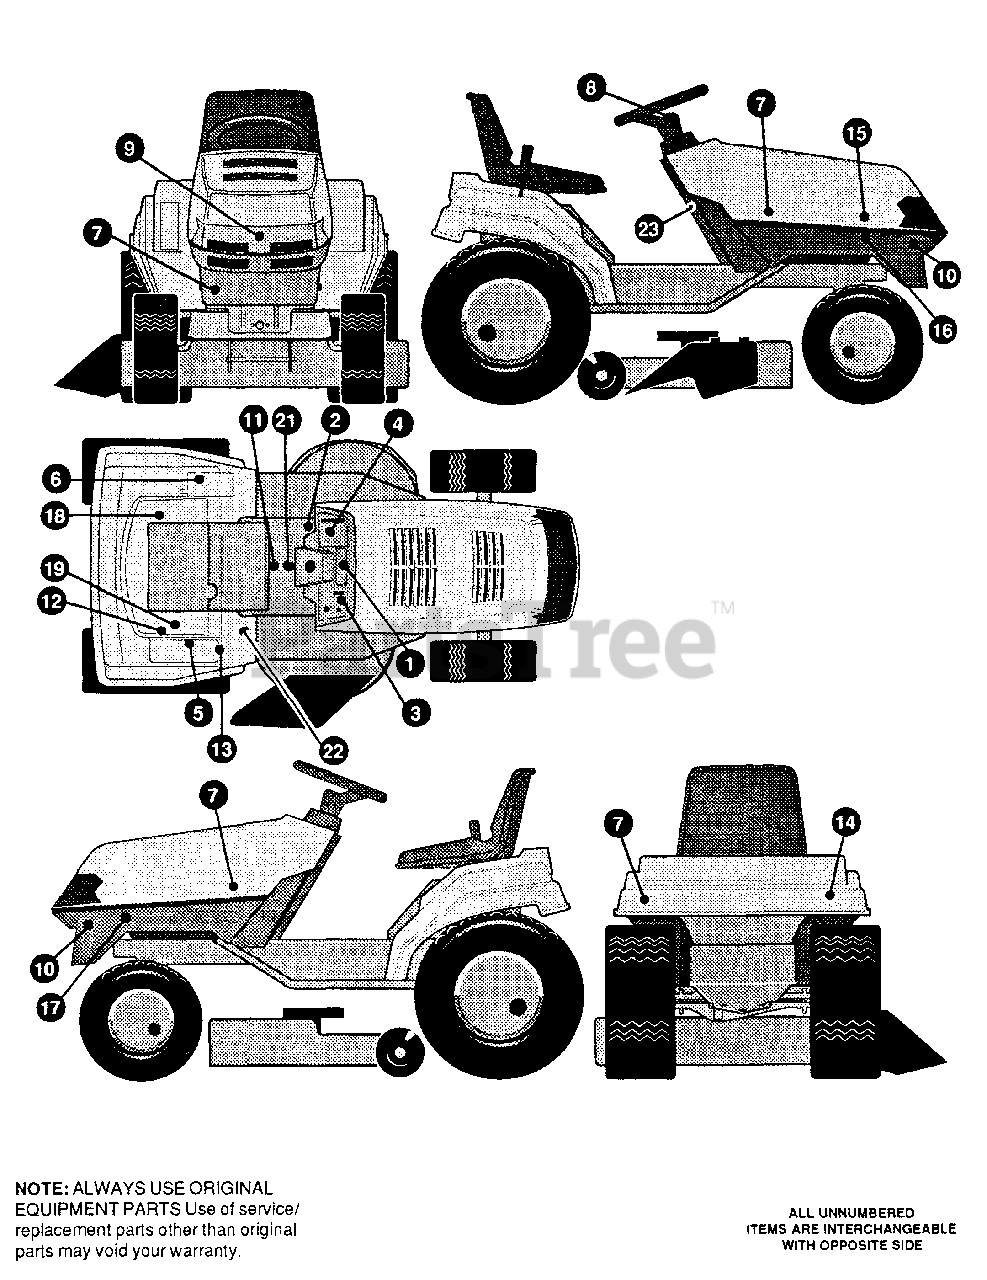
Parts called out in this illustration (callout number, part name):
1	DECAL, DASH, CHG, OIL, FUEL, ALL SYS
2	DECAL, DASH RH ISO
3	DECAL, DASH LEFT ENGLISH
4	DECAL INSTR FRENCH(CAN) ERO LT
5	DECAL SPEED HYDRO SIGNATURE
6	DECAL-DECK HEIGHT EURO ELEC/CL
7	DECAL, FENDER REAR, HOOD HYSQ.
8	DECAL, GUNSIGHT CENT. STEER
9	DECAL, GUNSIGHT CLEAR BACK
10	DECAL, WHEEL 4 STEER HUSQ.
11	DECAL, INSTRUC CONSOLE TOP
12	DECAL, 4WS PATENT NO. 5048853
13	DECAL, DEPRESS CL/BRAKE
14	DECAL, HYDROSTATIC
15	REFERENCE ONLY
16	DECAL, PIN STRIPE RH
17	DECAL, PIN STRIPE LH
18	DECAL, RELIEF VALVE OPERATION
19	DECAL, MODEL GENERIC HUSQ USA
20	REFERENCE ONLY
21	DECAL, OPER. INSTR. ERO TOP FRAME
22	DECAL, DANGER FRENCH
23	DECAL, PARK BRAKE
